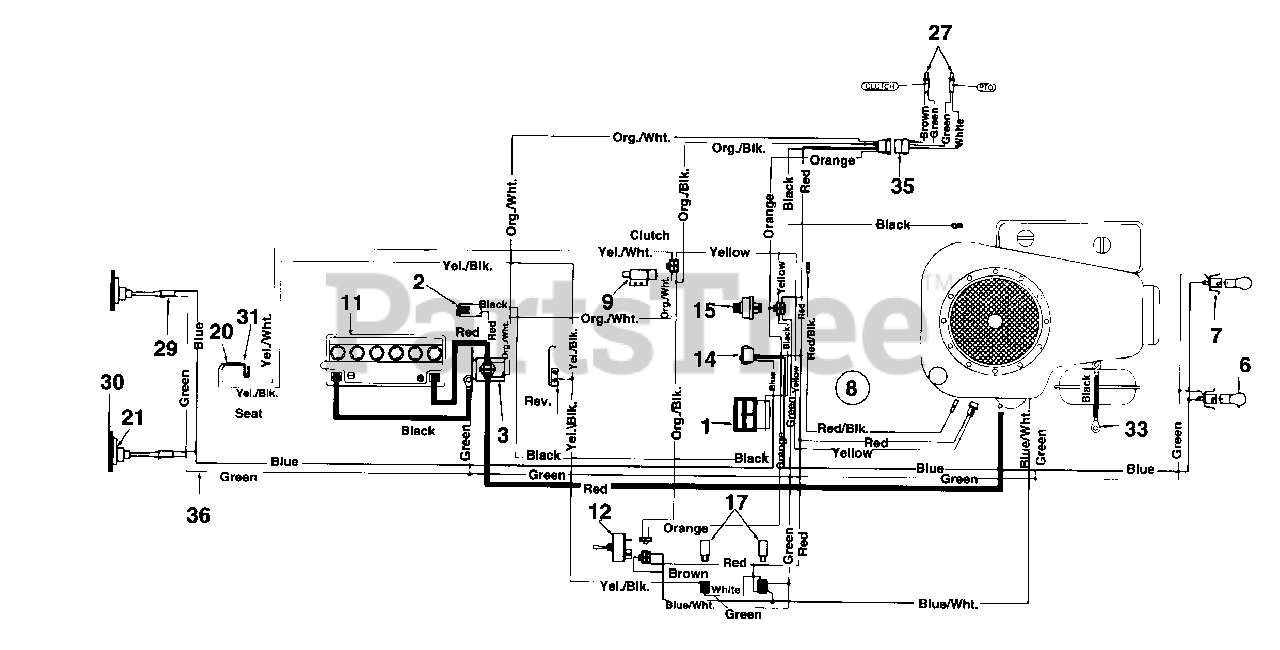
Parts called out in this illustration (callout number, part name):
1	Ammeter
2	Fuse 20 Amps
3	Solenoid
6	Bulb
7	Socket
8	Wire Harness
9	Safety Switch (Clutch)
11	Battery 12V
12	Switch (PTO)
14	Light Switch
15	Ignition Switch
17	Relay
20	Safety Switch (Seat)
21	Tail light
27	Bulb
29	Tail light Harness
30	Bulb
31	Safety Switch (Seat)
33	Wire 7.5" Lg.
35	Monitor Harness
36	Taillight Adapter Harness
